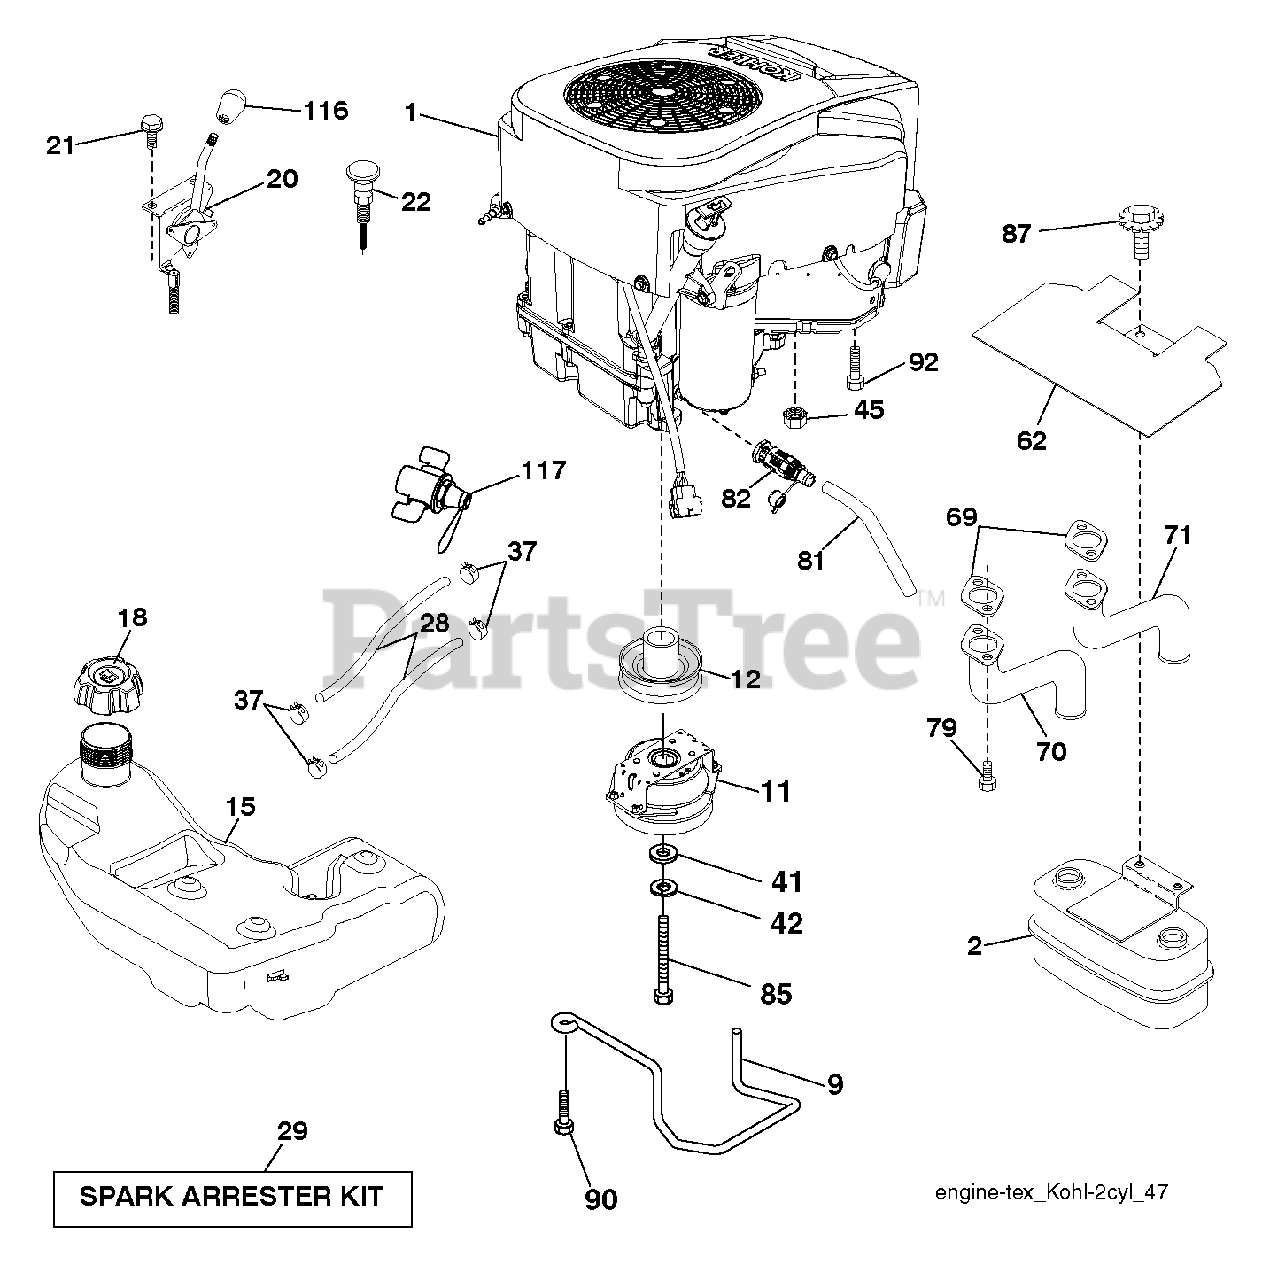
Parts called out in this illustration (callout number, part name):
2	MUFFLER.ASM.TWN.EXTNDED.DFLCTR
9	KEEPER BELT ENGINE
11	CLUTCH.OGURA.5.0PD.GT1.5A-EH07
12	PULLEY.ENGINE.TUFFTORQ
18	CAP.ASSY.FUEL.3".N-EPA.GRY.498
20	CONTROL.THROTTLE.PRO.KOHLER
21	SCREW.#10 X 0.750.BOS
22	CONTROL.CHOKE.ERGO.PUSH-IN.BLA
28	REPL BY 532 00 85-43
29	KIT.SPARK ARRESTOR 794945 B&S
37	HOSE CLAMP
42	LOCKWASHER
45	NUT
62	SHIELD.HEAT.MUFFLER
69	GASKET.EXHAUST.KOHL.CV18-CV26
70	PIPE.EXHAUST.LH.CV18/20
71	PIPE.EXHAUST.RH.CV18/20
79	SCREW.SOCKET HD.5/16-1
81	TUBE, DRAIN OIL ASM.
82	VALUE.OIL.DRAIN
85	BOLT HEX 7/16-20 X 3.75 GR. 5
87	Bolt, 5/16-18 X 1-3/4
90	SCREW 3/8-16X1
92	SCREW 3/8-16X1
116	KNOB - SHIFT
117	VALVE FUEL RESERVE
